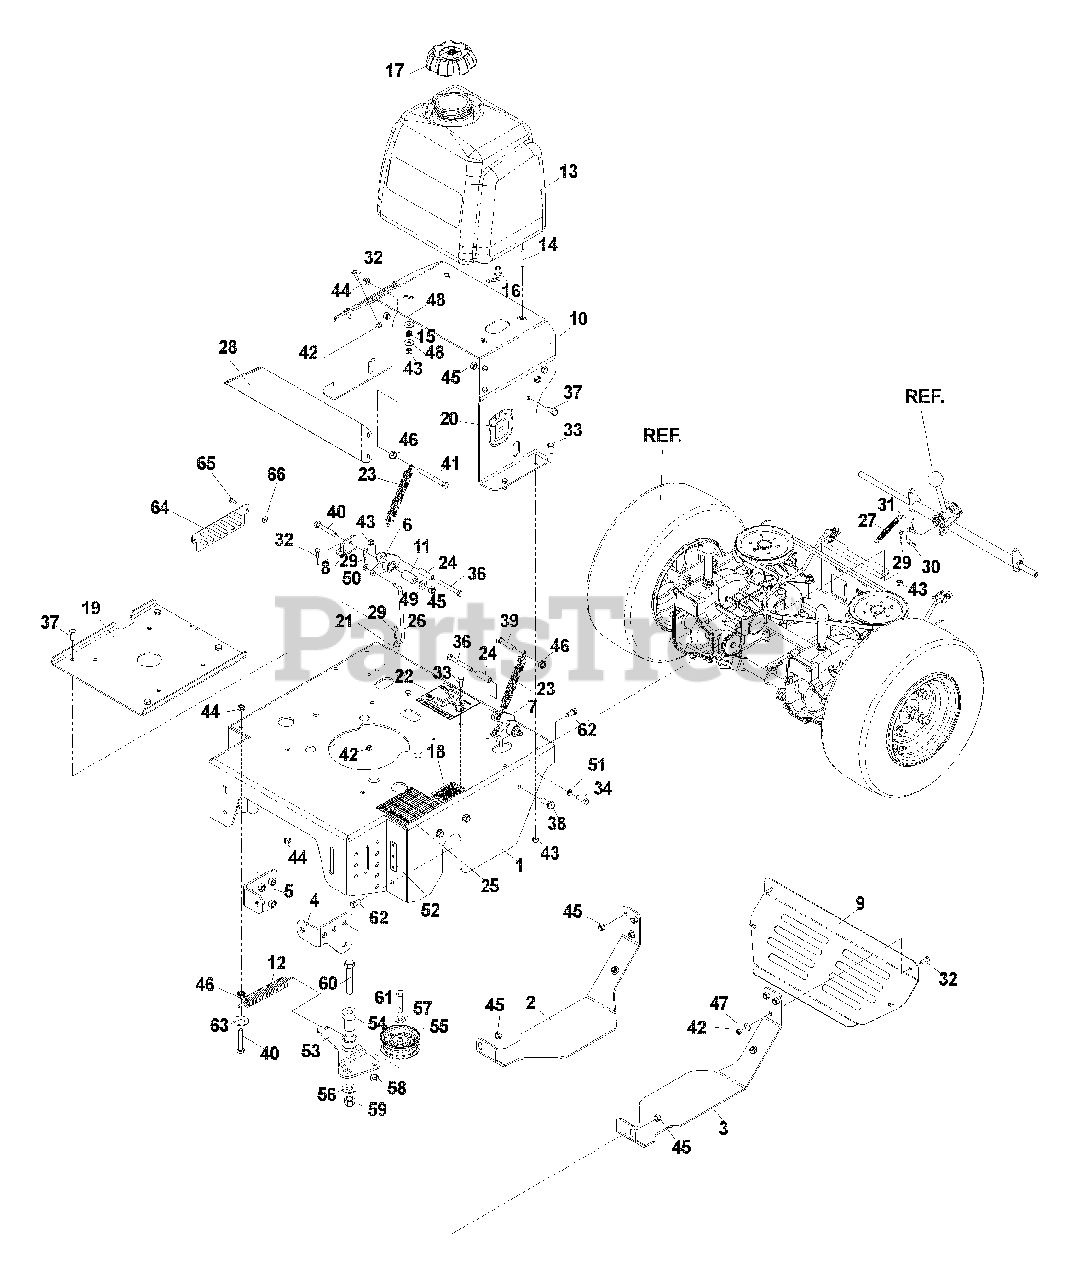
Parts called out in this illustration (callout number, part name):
1	REAR DECK W/DECALS
2	SKID PLATE, RIGHT
3	SKID PLATE, LEFT
4	NUT PLATE, LEFT
5	NUT PLATE, RIGHT
6	BELLCRANK, RIGHT, ETS
7	BELLCRANK, LEFT, ETS
8	CONTROL BRACKET
9	REAR GUARD
10	TANK SUPPORT
11	SLEEVE BUSHING
12	TRACTION SPRING
14	STUD, 5/16C
15	SPRING, TANK MOUNT
16	HOSE BARB, 90°
17	FUEL CAP
18	DECAL, PROP 65
19	PLATE, ENGINE
20	DECAL, SMALL CROWN
21	DECAL, DANGER, BELT DRIVES
22	DECAL, BYPASS/ BRAKE
25	DECAL, HEIGHT
26	CONTROL LINKAGE
29	HAIRPIN COTTER
30	BRAKE ENGAGEMENT LINKAGE
31	PIN COTTER, 3/32 X 3/4
32	HCS, 1/4-20 X 3/4
33	HCS, 5/16-18 X 3/4
34	HCS, 5/16-18 X 1
36	HCS, 5/16-18 X 2 3/4
37	HCS, 3/8-16 X 3/4
38	HCS, 3/8-16 X 1
39	HCS, 3/8-16 X 2 1/2
40	HCS, 3/8-16 X 2 1/4
41	HCS, 3/8-16 X 3 1/2, GR8
42	NUT, 1/4C, NYLOC
43	NUT, 5/16C, NYLOC
44	NUT, 3/8C, CENTERLOCK
45	NUT, 3/8C, NYLOC
47	WASHER, 1/4
48	WASHER, 5/16
49	WASHER, 3/8
50	WASHER, 5/16, SAE
51	LOCK WASHER, 5/16
52	DECAL, POSITION
53	IDLER ARM, WELDMENT
54	IDLER SPINDLE
55	IDLER PULLEY
56	WASHER, 1/2
57	WASHER, 5/16
58	NUT, 3/8C, CENTER LOCK
59	NUT, 1/2C, NYLOC
60	HCS, 1/2-13 X 2 3/4
61	HCS, 3/8-16 X 1 3/4
62	HCS, 3/8-16 X 1
63	WASHER, 1/2, SAE
65	SCREW, #10-24 X 5/8, WASHER HEAD
66	WASHER, #10
